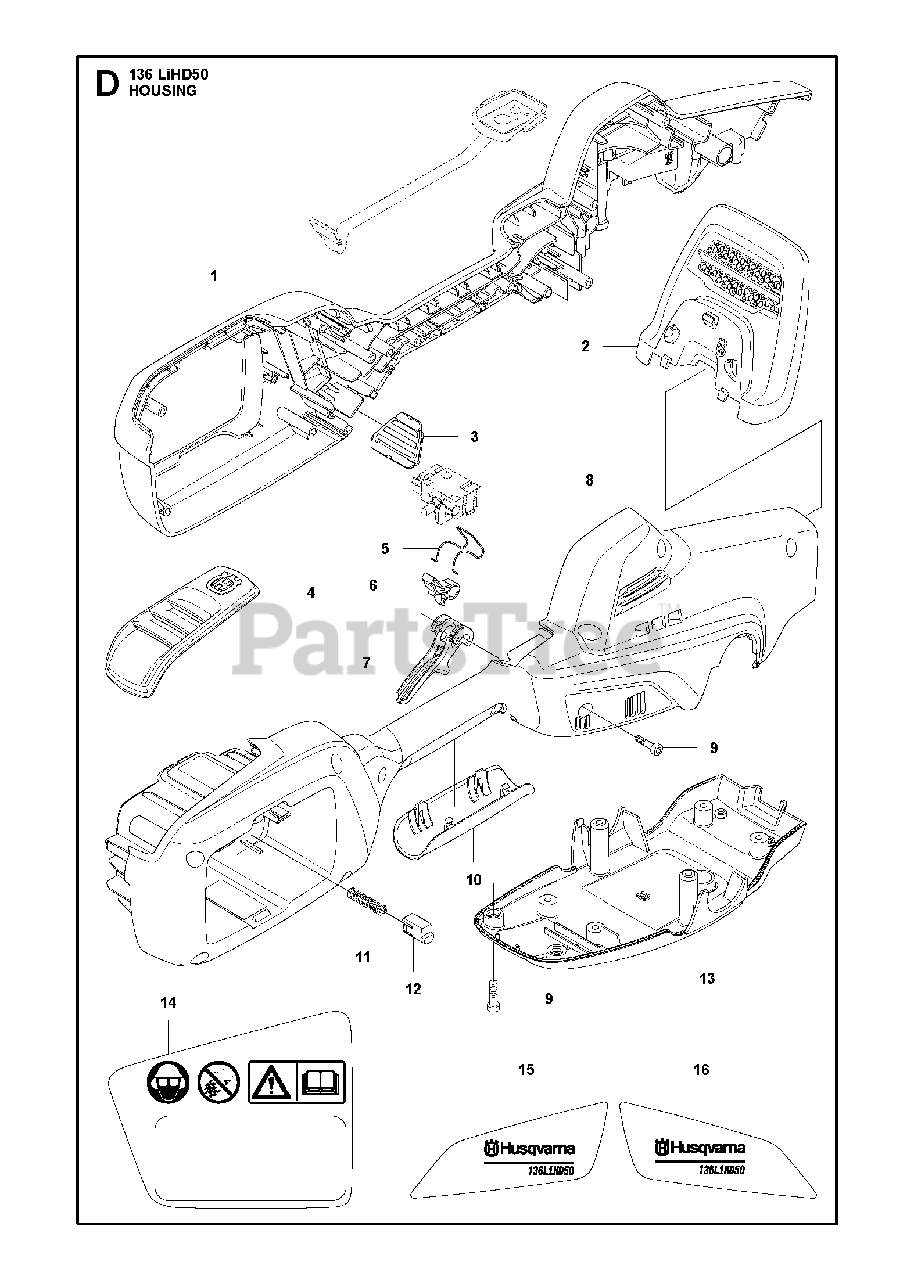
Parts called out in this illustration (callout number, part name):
3	COVER AIR INLET
9	SCREW
10	HANDLE SHELL
11	SPRING
12	PUSH BUTTON
13	SKID PLATE, FRONT
14	TYPE PLATE
